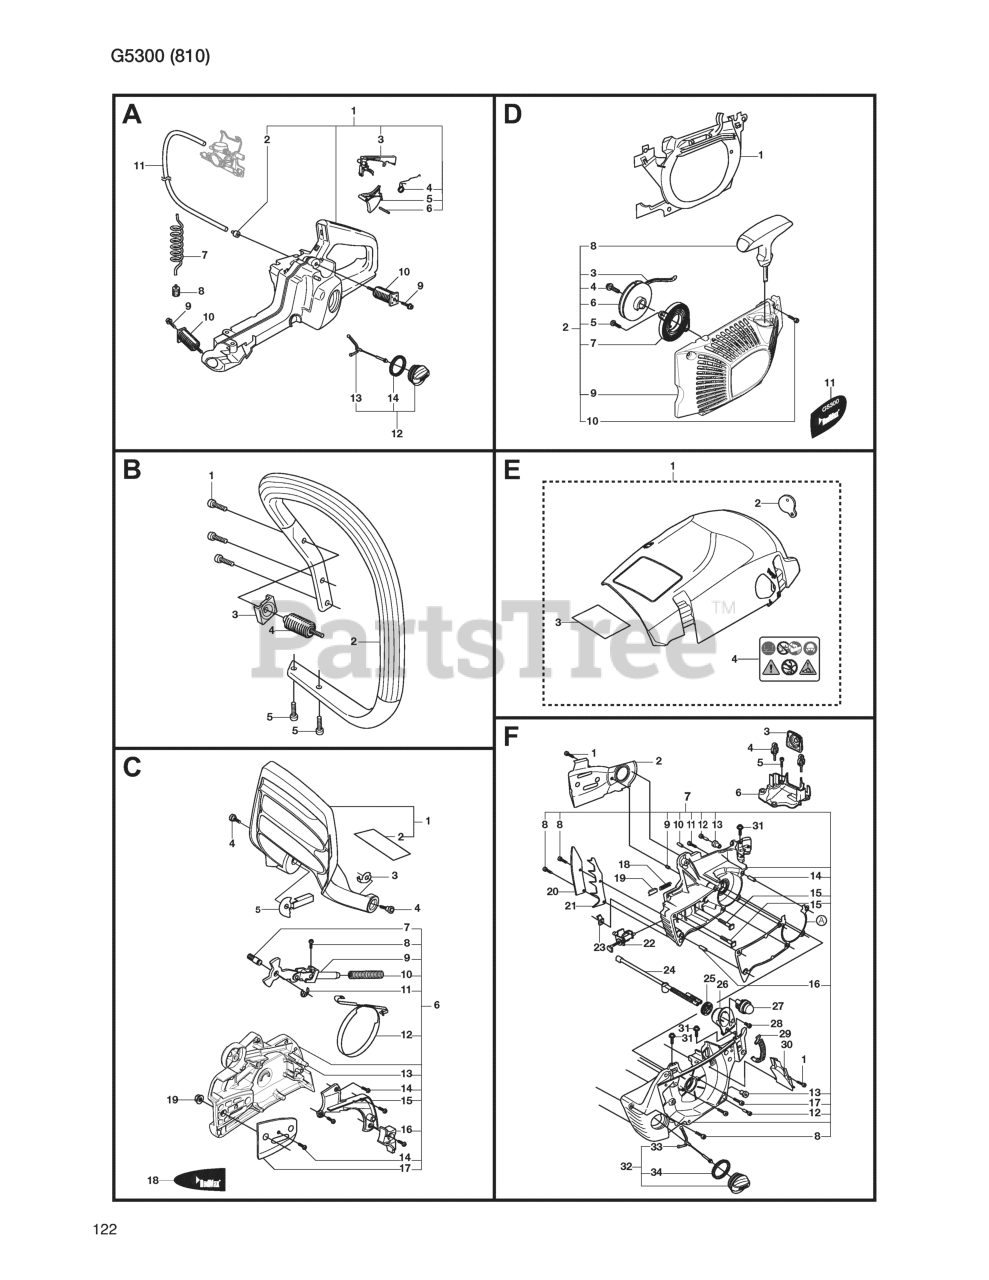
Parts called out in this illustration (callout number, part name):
A1	FUEL TANK ASSY
A2	TANK VENT ASSY
A3	THROTTLE LOCKOUT
A4	RECOIL SPRING
A5	THROTTLE TRIGGER
A7	FUEL HOSE
A8	FILTER
A10	ANTI-VIBRATION ELEMENT
A11	FUEL HOSE
A12	TANL CAP ASSY
A14	SEALING
B4	ANTI-VIBRATION ELEMENT
C1	HAND GUARD ASSY
C2	HEAT PROTECTOR
C3	WEAR WASHER
C5	WEAR PROTECTION
C6	CHAIN BRAKE ASSY
C7	PIN KNEE JOINT
C8	SCREW CCRPANT
C9	KNEE JOINT ASSY
C10	BRAKE SPRING
C12	BRAKE BAND ASSY
C13	GUIDE BUSHING
C14	SCREW CCRPANT
C15	OIL HOSE
C16	WEAR PROTECTION
C17	COVER PLATE
C19	NUT FLANGE
D1	AIR CONDUCTOR
D2	STARTER ASSY
D3	STARTER CORD
D5	SCREW CCRPANT
D6	STARTER PULLEY
D7	SPRING CASSETTE ASSY
D8	STARTER HANDLE
D9	STARTER HOUSING
E1	CYLINDER COVER ASSY
E2	COVER
E3	HEAT PROTECTOR
F2	CHAIN GUIDE PLATE
F4	CARBURETOR MOUNTING
F6	CARBURETOR AREA BASE
F7	CRANKCASE ASSY
F13	LATERAL SUPPORT
F14	GUIDE BUSHING
F15	BAR BOLT
F16	GUIDE BUSHING
F17	SCREW IHSCM
F18	POSITION SPRING
F22	CHAIN TENSIONER
F23	CHAIN CATCHER PIN
F24	HOSE
F27	PRIMER HOUSING
F30	AIR NOZZLE
F32	TANK CAP ASSY
A	GASKET KIT
